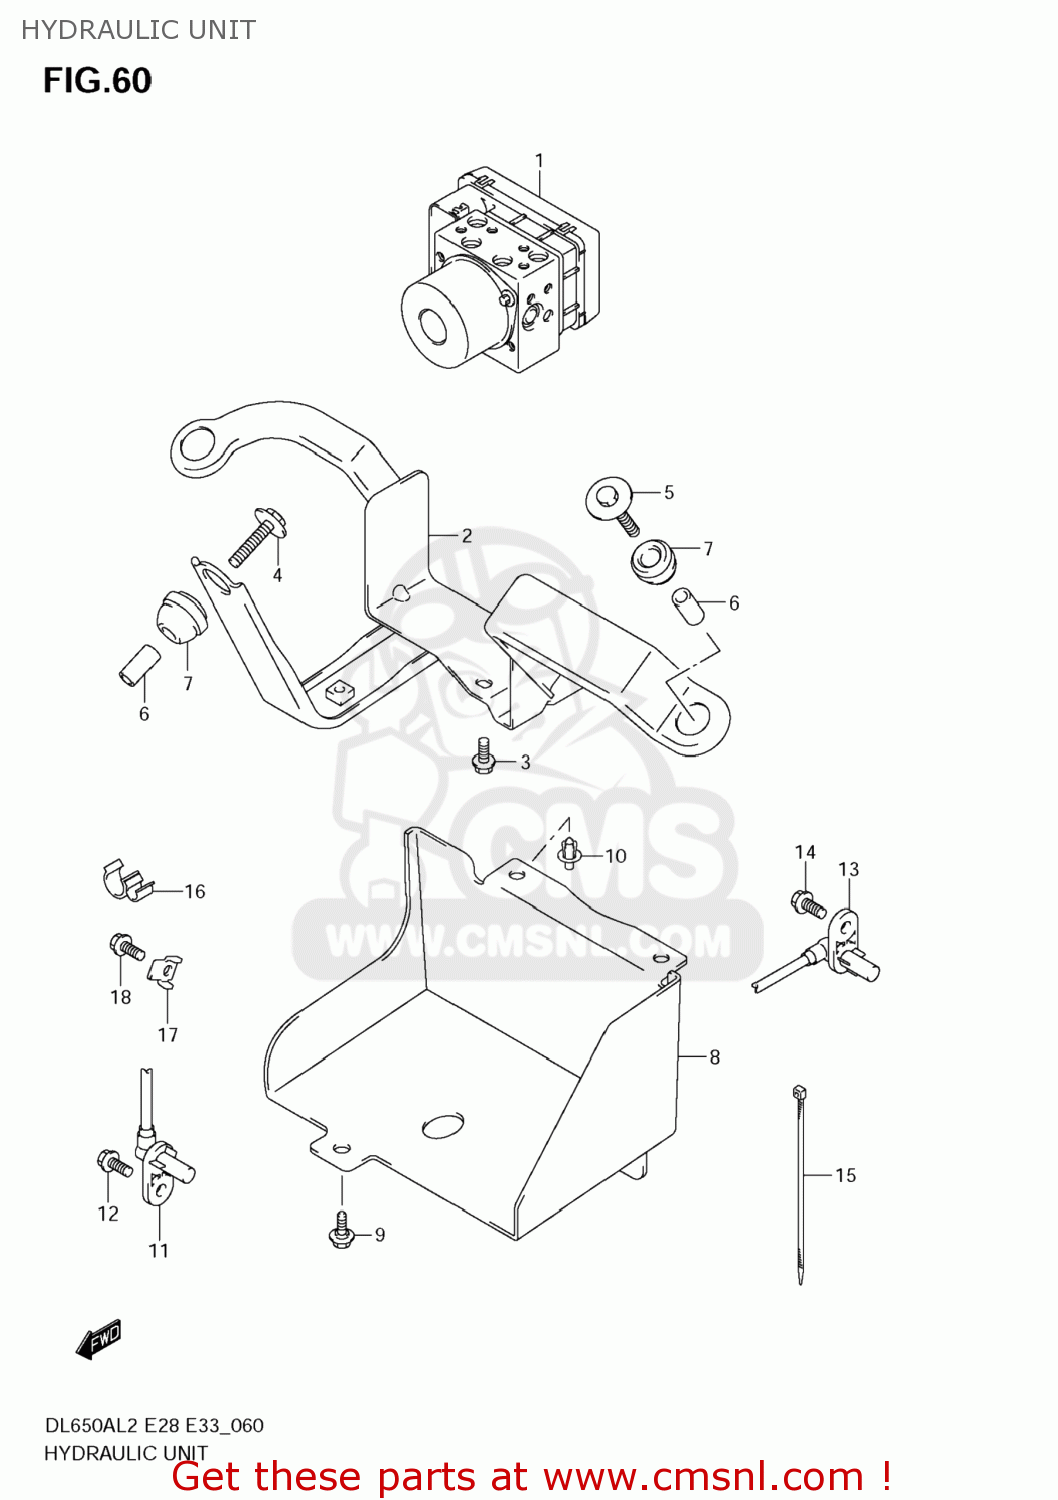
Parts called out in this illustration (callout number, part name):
1	UNIT ASSY,HYDR
2	HOLDER,HYDRAULIC UNIT ABS
3	BOLT
4	BOLT(6X30)
5	BOLT(6X37)
6	SPACER(6.5X10X20)
7	CUSHION
8	COVER,HYDR ABS UNIT
9	BOLT(6X16)
10	CLIP(BLACK)
11	SENSOR,FR WHEEL ABS
12	BOLT
13	SENSOR,RR WHEEL ABS
14	BOLT
15	CLAMP(L:145)
16	CLAMP
17	GUIDE,SENSOR LEAD
18	BOLT
